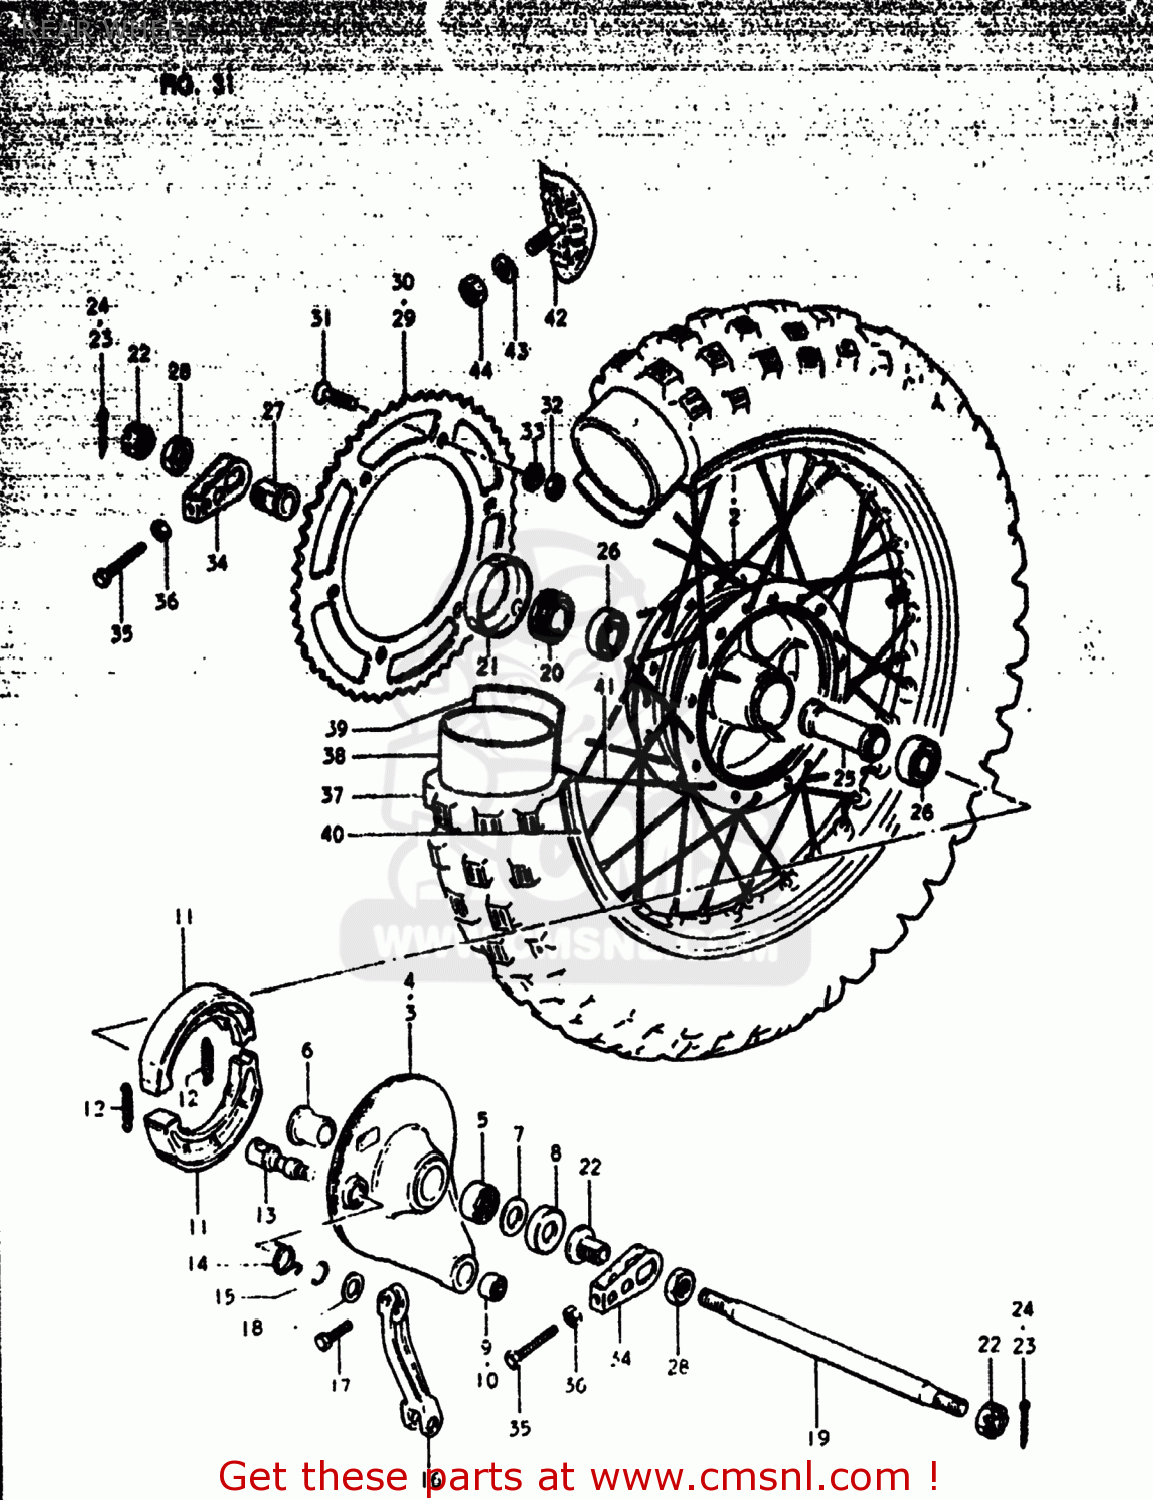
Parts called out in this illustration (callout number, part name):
1	HUB,REAR
2	HUB,REAR
3	PANEL,REAR HUB
4	PANEL SET,REAR HUB
5	BEARING(22X29X25)
6	SPACER,REAR HUB PANEL
7	WASHER
8	COVER, PANEL DUST SEAL
9	BUSH
10	SPHERICAL BEARING,TORQUE
11	SHOE,BRAKE
12	SPRING(L:34)
13	CAM,FR BRAKE
14	SPRING
15	O RING(D:2.5,ID:11.4)
16	LEVER,RR BRAKE CAM
17	BOLT
18	WASHER(12.5X20X1)
19	AXLE,REAR
20	SPACER,REAR AXLE,RIGHT
21	HOLDER,REAR AXLE SPACER
22	NUT
23	PIN 30X40
24	COTTER PIN
25	SPACER,REAR HUB BEARING
26	BEARING
27	SPACER,CHAIN ADJUSTER
28	NUT
29	SPROCKET,REAR
30	SPROCKET,REAR
31	SCREW(8X33.5)
32	NUT
33	WASHER
34	ADJUSTER,CHAIN
35	BOLT
36	NUT
37	TIRE
38	TUBE ASSEMBLY,WHEEL,INNER
39	PROTECTOR,INNER TUBE
40	RIM,REAR WHEEL
41	SPOKE SET,REAR
42	STOPPER,BEAD
43	WASHER
44	NUT
